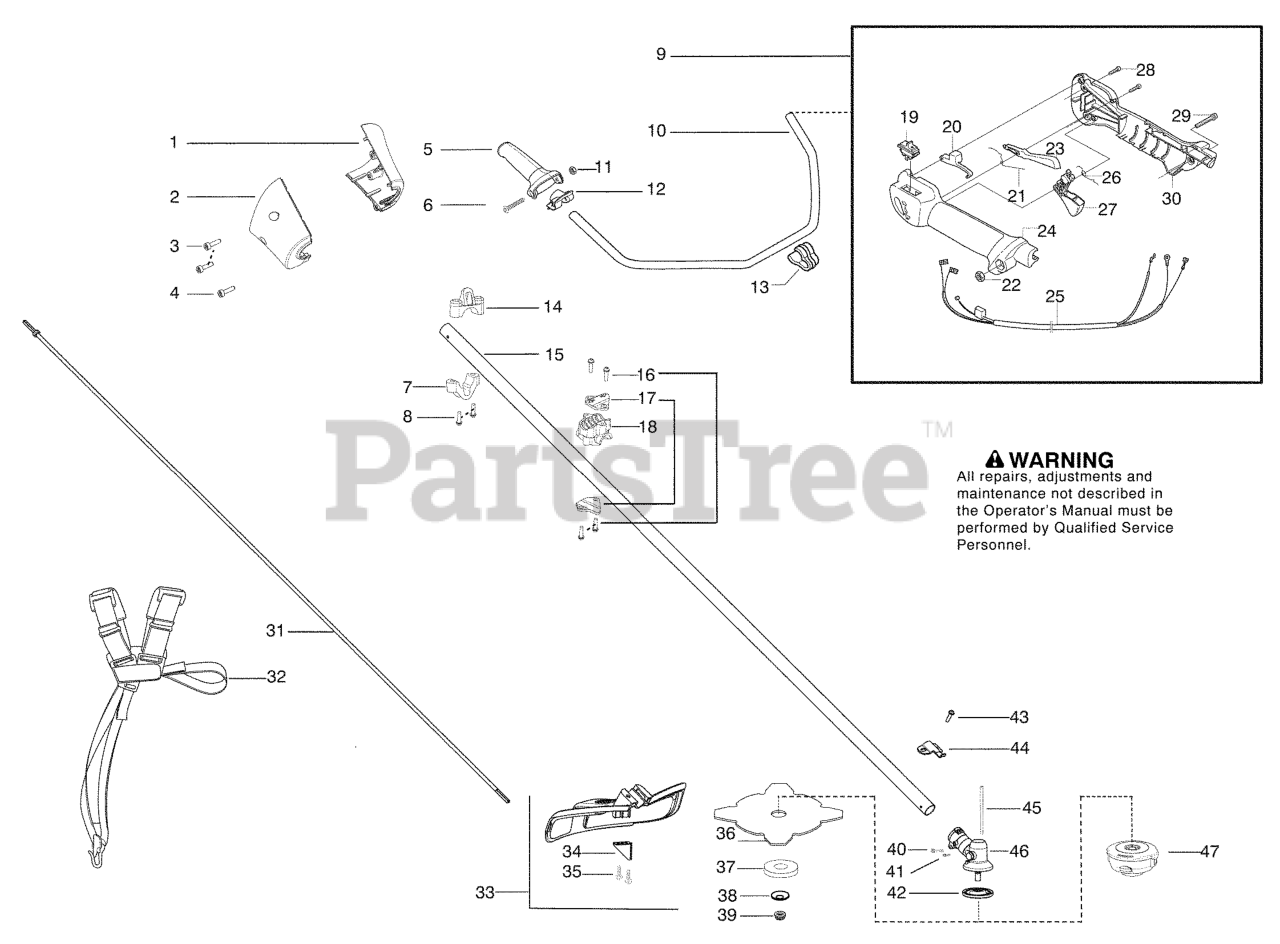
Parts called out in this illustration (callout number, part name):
1	NOSE CONE BH LEFT
2	NOSE CONE BH RIGHT
4	SCREW M4 X 1.75 PT 16MM
7	CLAMP HARNESS LOWER
9	ASSY THROTTLE HOUSING
14	CLAMP HARNESS UPPER
15	KIT DRIVESHAFT
17	CLAMP BRACKET
19	STOP BUTTON
20	LOCKOUT STARTER THROTTLE
23	THROTTLE LOCKOUT
25	ASSY CABLE WIRE HARNESS
27	THROTTLE CONTROL
29	SCREW
31	FLEXSHAFT 57"
32	HARNESS DUO
33	KIT COBI SHIELD
34	Limiter - Line
36	Blade - Grass
37	SUPPORTING CUP
38	SUPPORT FLANGE
39	GEARHEAD NUT - BRUSHCUTTER
40	SCREW - CARB. ADAPTOR
42	DRIVE DISC
43	SCREW 1/4-20 X 7/8 (TAP
44	BRACKET SHIELD STRAIGHT SHAFT
45	LOCKING PIN
46	ASSY GEARBOX
47	T25 TRIM HEAD 10MM LH
